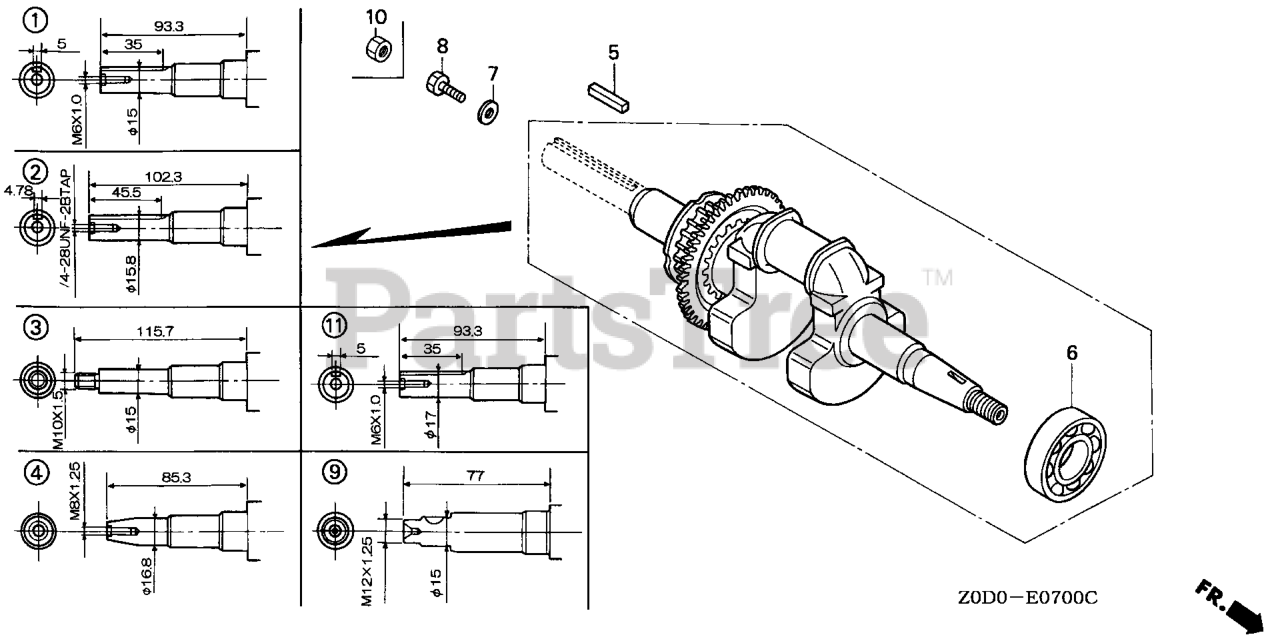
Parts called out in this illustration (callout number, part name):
2	CRANKSHAFT
5	KEY (4.78X4.78X38)
6	BEARING, RADIAL BALL (6204)
